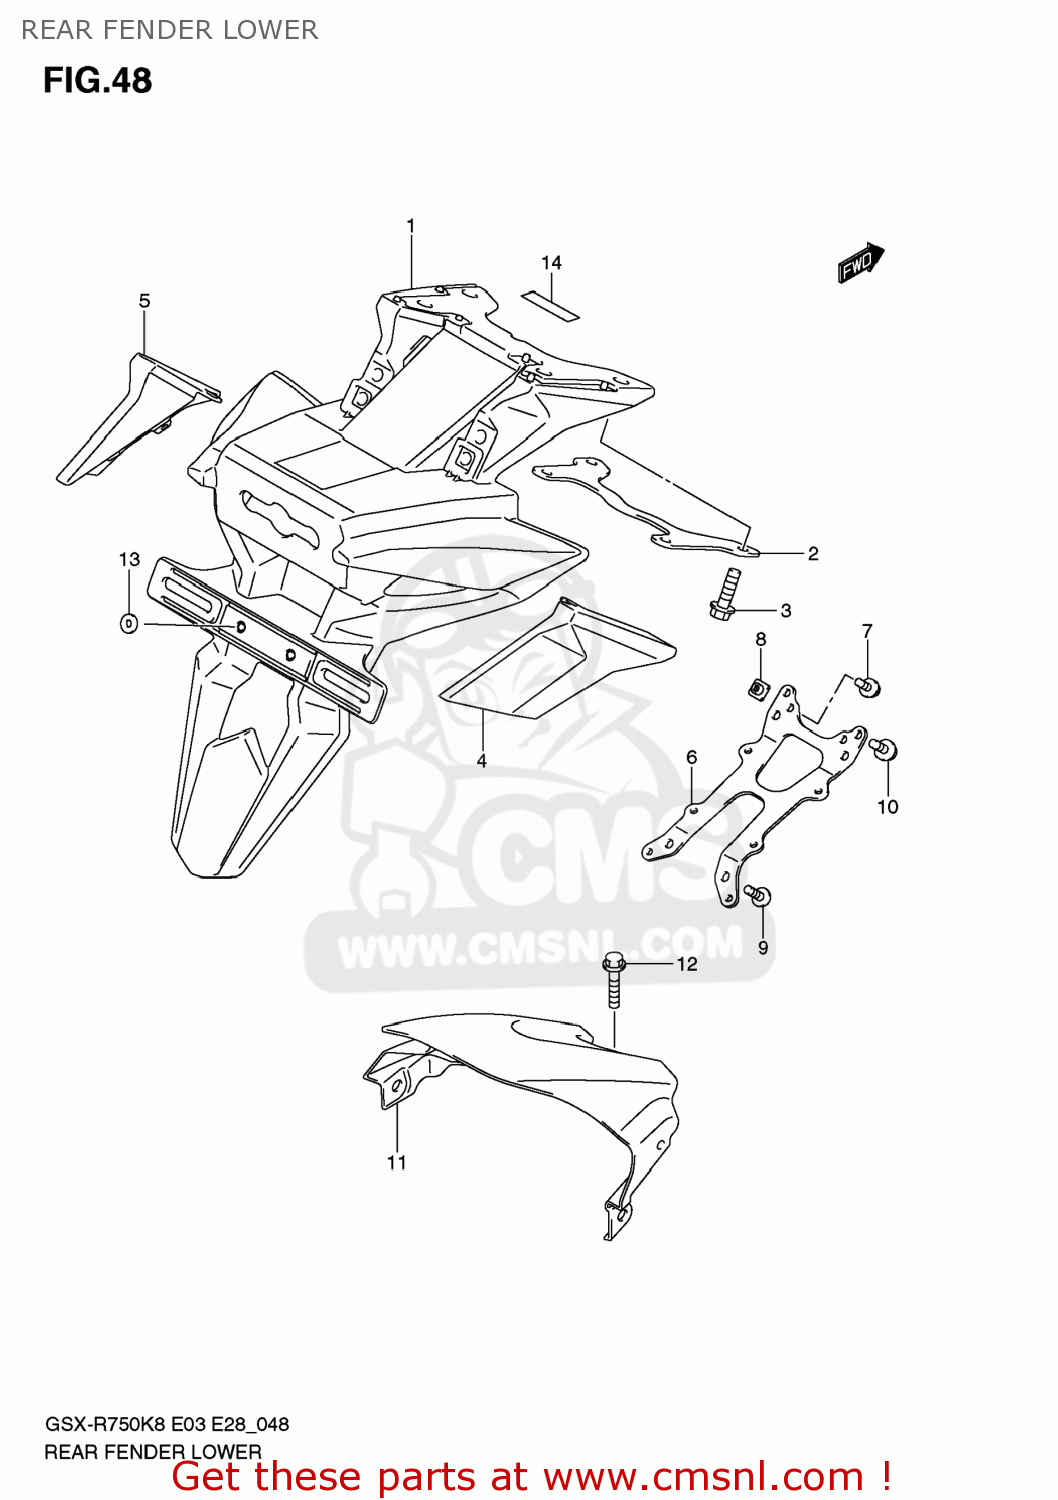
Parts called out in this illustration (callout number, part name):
1	FENDER,RR RR
2	PLATE,RR FENDER RR
3	BOLT(6X25)
4	COVER,RR FENDER RR,R
5	COVER,RR FENDER RR,L
6	BRACKET,RR FENDER RR
7	SCREW(6X12)
8	NUT
9	SCREW
10	BOLT
11	FENDER,RR LWR
12	BOLT(6X14)
13	WASHER
14	CUSHION,PANEL NO.1
